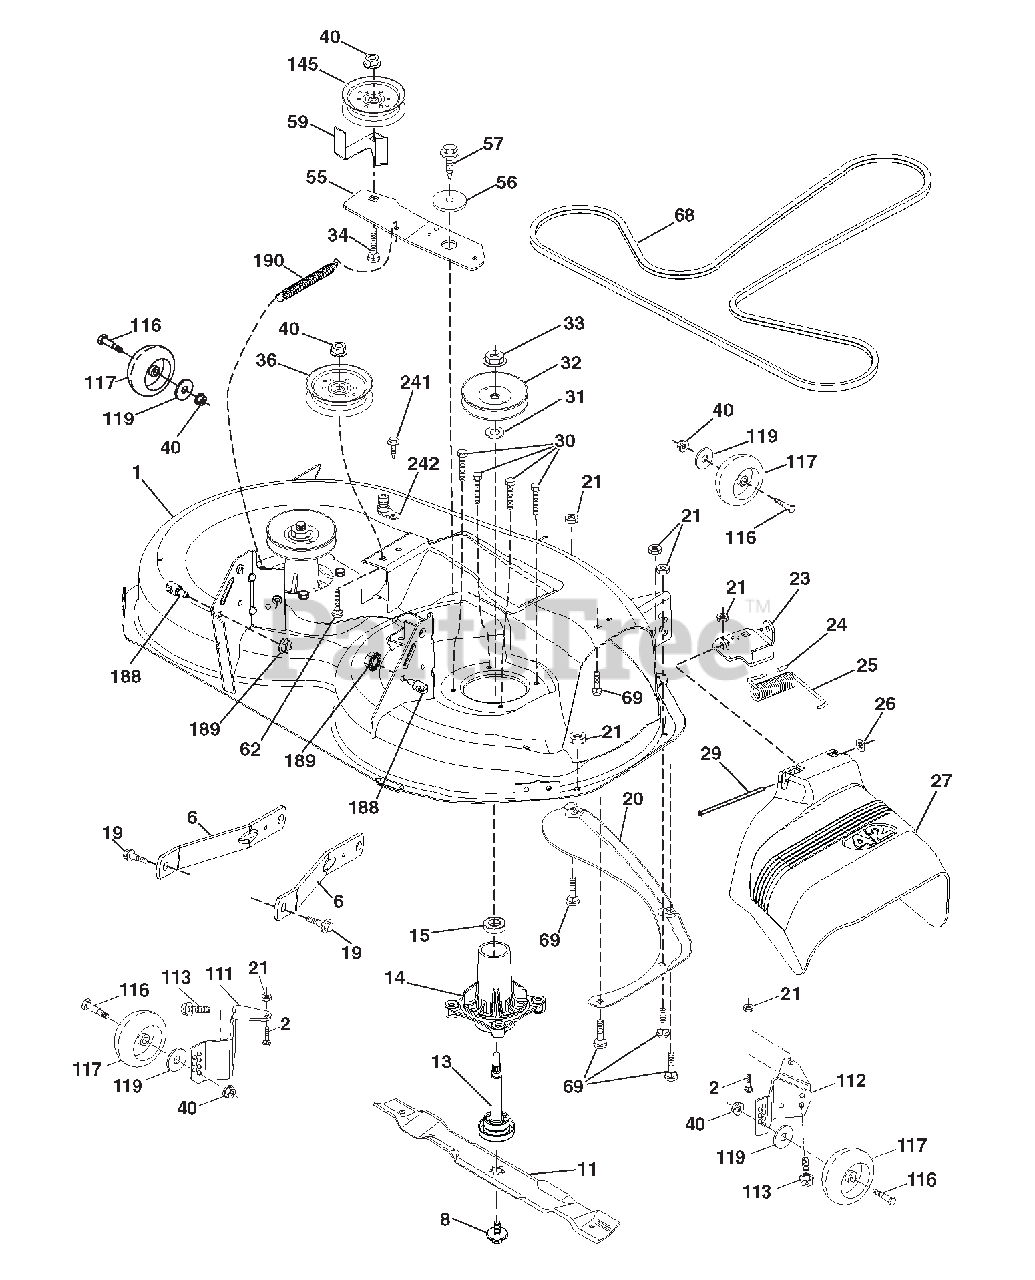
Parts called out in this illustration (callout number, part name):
1	MOWER HOUSING
6	ARM.SUSPENSION.MOWER.REAR.LD
8	BOLT/WASHER ASM.7/16-20.UNF
11	BLADE.MOWER.42"HI LIFT PREMIUM
13	SHAFT ASM.MNDRL.N/GREASEABLE38
14	HOUSING.MANDREL.4PT.SERVICE
15	BEARING.BALL.MANDREL
19	BOLT.SHOULDER
20	BOLT.SHOULDER
21	BAFFLE.VORTEX.42.STD/HEAVY DTY
23	Nut, Hex, Crownlock 5/16-18
24	BRACKET.DEFLECTOR.38/42"2005
25	SPRING.TORSION.DFL.38/42/46.GR
26	NUT.PUSH.PHOS.& OIL
27	SHIELD.DEFLECTOR.
29	ROD.HINGE.42/46"
30	SCREW.THD ROLL.DOD PT.HEX
31	WASHER.SPACER.MANDREL
32	MANDREL.PULLEYS.42,44,50
33	NUT.FLANGE.LOCK.TOP
34	BOLT.CARR.SH.3/8-16X1-1/2.GR5
36	PULLEY.IDLER.4.50.RAW
40	Nut, Hex, Flangelock 3/8-16
55	IDLER.ARM
56	SPACER.RETAINER
57	SCREW.3/8-16X1.SMGML.TAP/R.BLK
59	GUARD.TUV.IDLER
62	BOLT.RD.HD.SQ.NK.3/8-16UNC X 2
68	V-Belt, 42" Mower
69	BOLT.RDHD.SQNK.5/16-18 X 5/8
111	BRACKET WHEEL GAUGE LH
112	BRACKET WHEEL GAUGE RH
113	BOLT.5/16-18HEX.WHS.HD.LCKSERR
116	BOLD SHLD "A" 2.41 "B" 1.66
117	WHEEL.GAGE.HALF.SPOKED
119	Washer 3/8 x 7/8 x 14 Ga.
145	PULLEY.IDLER 48"PRIMARY
188	STUD.FASTNER.W/'D'ANTI-ROTATIO
189	Nut, Lock Hex Flange 5/16-18 u
242	PORT WASHOUT
